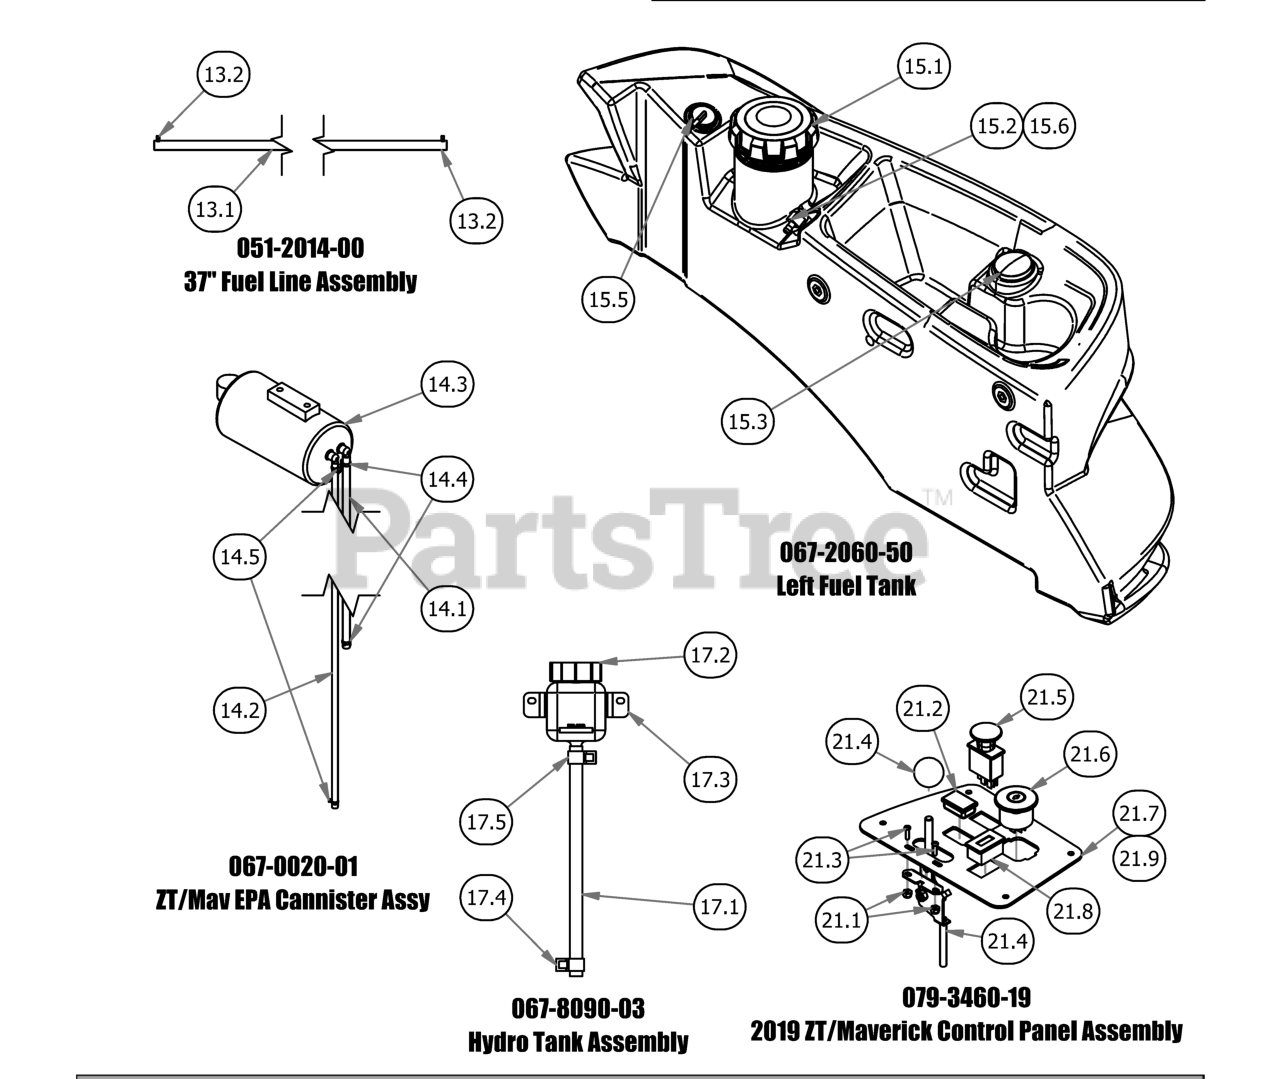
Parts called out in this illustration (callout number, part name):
13.1	37" 1/4 Fuel Line
13.2	1/4 Fuel Hose Clamp
14.1	1/4" Vinyl Tubing, 46" Long
14.2	3/16" Vinyl Tubing, 55" Long
14.3	Carbon Canister
14.4	3/16 Vinyl Clamp
14.5	3/16" Vinyl Hose Clamp
15.3	Fuel Gauge w/Grommet
15.5	Rollover Valve W/Grommet
15.6	Pick-Up Grommet
17.1	ZT/Maverick Hydro Tank Hose
17.2	Hydraulic Tank Cap
17.3	350ml Expansion Tank
17.4	3/8" Hose Clamp
17.5	1/2 Hose Clamp
21.1	10-24 Nylon Insert Locknut Zinc Orange Nylon
21.2	Light Plug
21.3	10-24 X 5/8 BS Button Head Bolt
21.4	Throttle Lever Assembly
21.5	PTO Engager
21.6	Ignition Switch
21.7	Control Panel
21.8	Tachometer
21.9	2018 MZ/Magnum/ZT/Maverick Control Panel Decal
